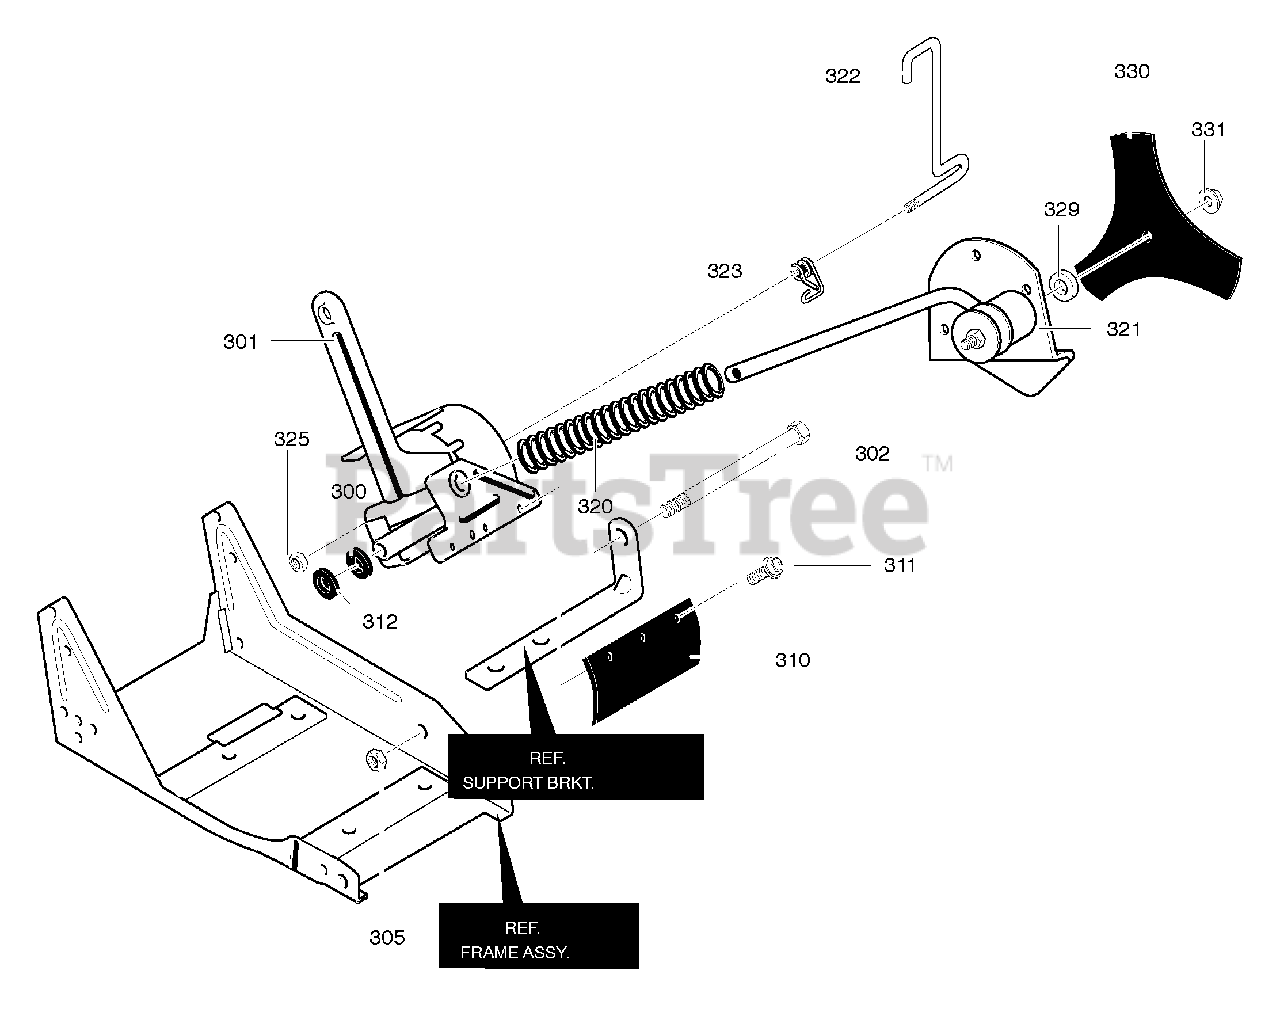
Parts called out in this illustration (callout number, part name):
300	Flatwasher
301	Quill Support
302	Bolt, 3/8- 16
305	Nut, 3/8- 16
310	Rubber Deflector
311	Screw, 10-16x1.50
312	Flatwasher
320	Spring, Compression
321	Quill Assembly
322	Lever, Index
323	Spring, Torsion
325	Nut, 5/16-18
329	Flatwasher
330	Blade, Edger
331	Nut, 1/2-20
